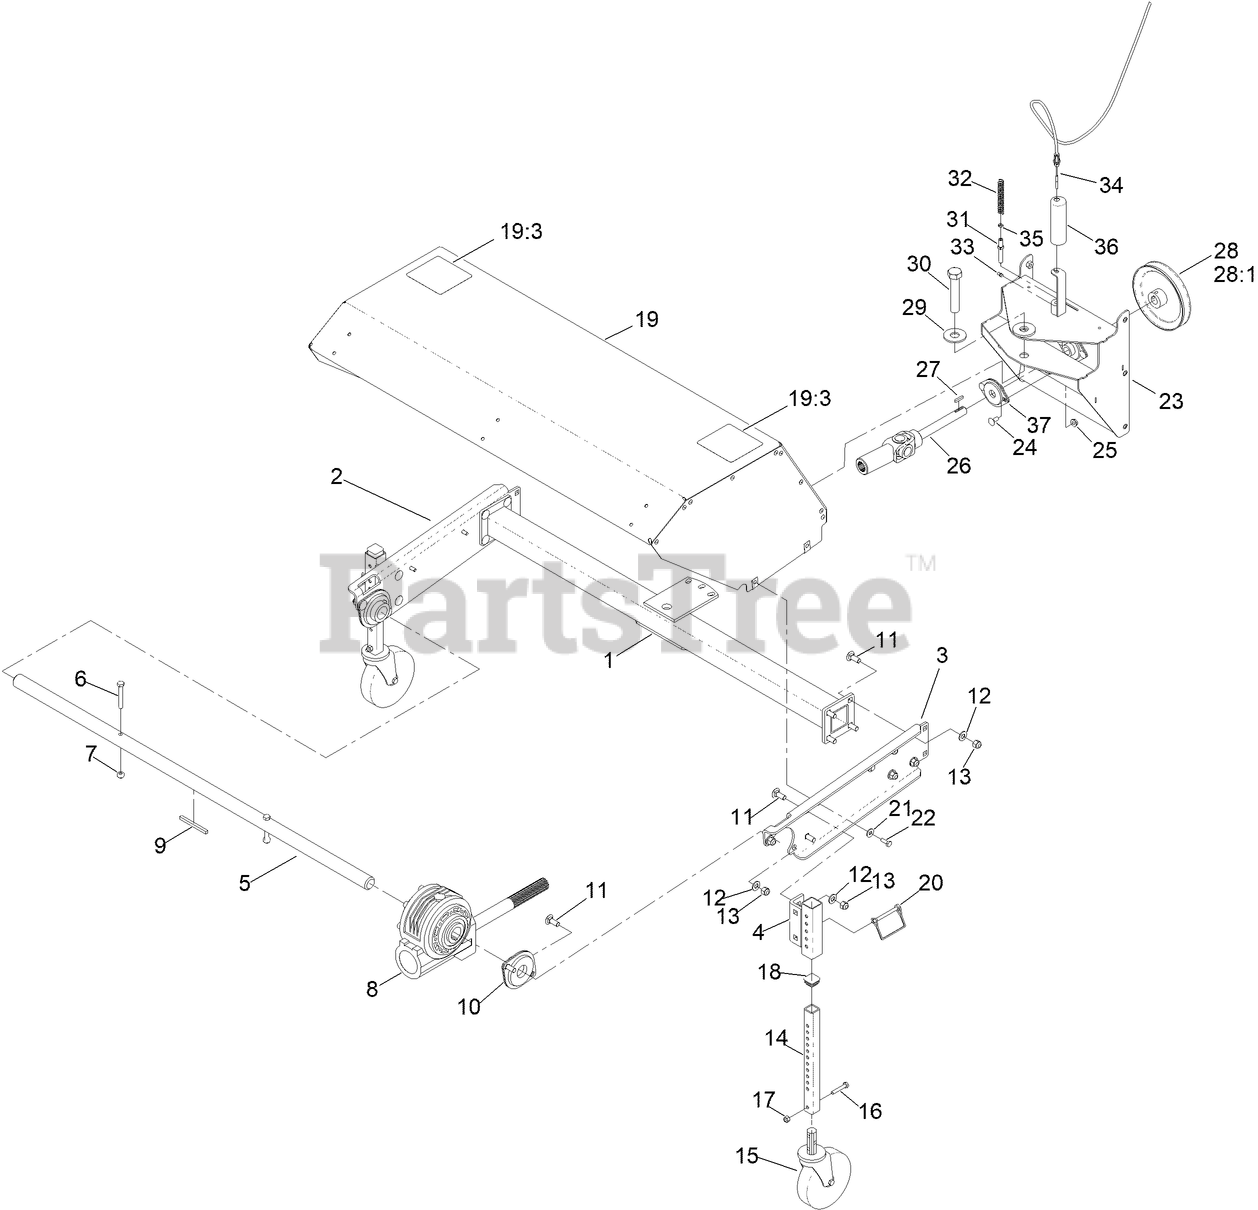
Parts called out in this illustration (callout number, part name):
2	ARM-RIGHT
3	ARM-LEFT
4	CASTER-BRACKET
6	SCREW-HH
7	NUT-HEX
8	GEARBOX-WORM
9	KEY-STRAIGHT
10	BEARING-FLANGE
11	SCREW-CARR
12	WASHER-FLAT
13	NUT-HEX
14	TUBE-SQUARE, HEIGHT ADJUST
15	CASTER-WHEEL
16	SCREW-HH
17	NUT-HEX
19	BROOM HOOD ASM
19:3	DECAL-WARNING
20	PIN-WIRE, LOCK
21	WASHER-FLAT
22	SCREW-HH
23	FRAME-MOUNTING
24	BOLT-CARR
25	NUT-HF
26	SHAFT-DRIVE
27	KEY-ROUND END
28	PULLEY-IMPELLER
28:1	SETSCREW
29	WASHER-FLAT
30	SCREW-HH
31	PIN-SWING
32	SPRING-COMPRESSION
33	FITTING-GREASE
34	CABLE-ANGLE, BROOM
35	NUT-HEX
37	BEARING-SHAFT
